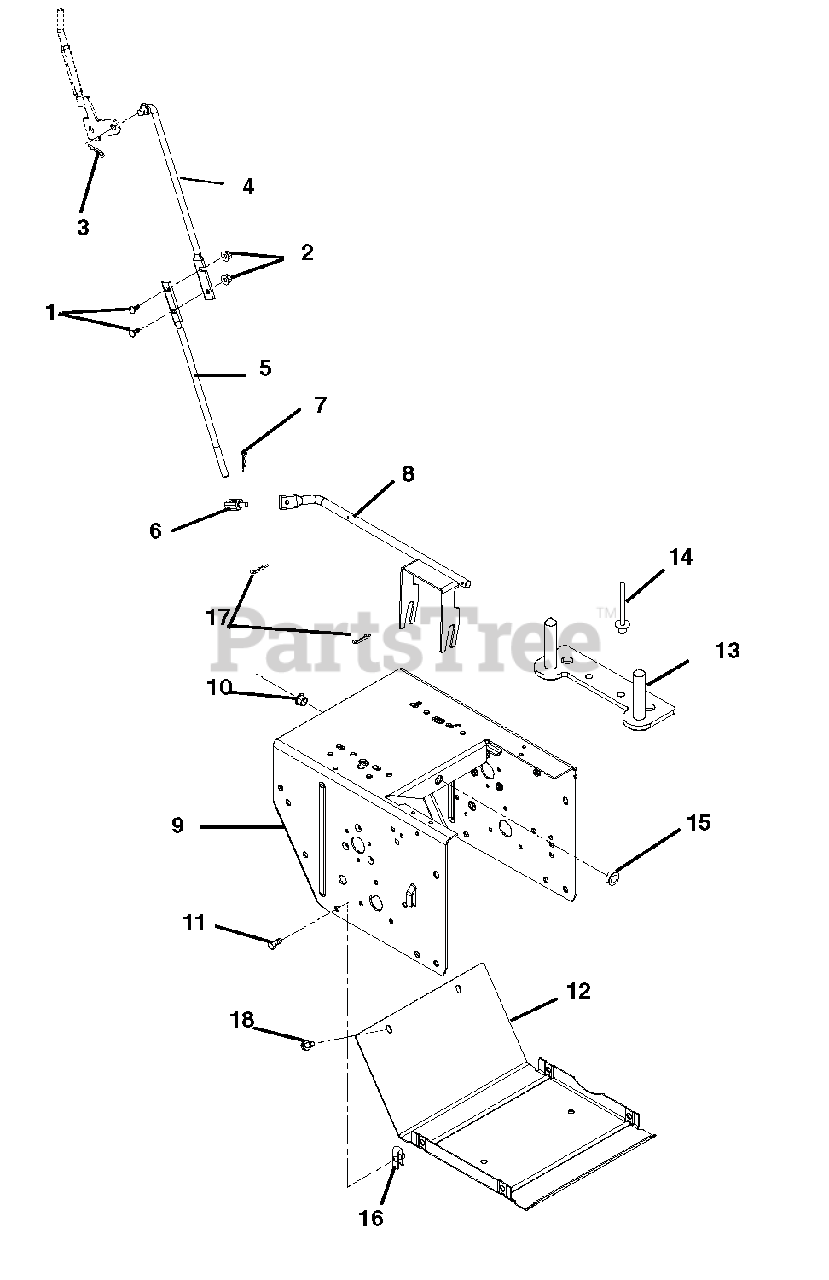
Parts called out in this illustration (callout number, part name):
1	@BLT-RDHDSQNK .25-20X.75 G5YZ
2	@NUT-LK-TOP-FLG .25-20 YWZC
3	PIN-HAIR, ENDRIES #25 YWZC
4	ROD, SHIFT-UPPER
5	ROD, SHIFT-LOWER
6	PIVOT,SHIFT ROD .375-16(TRUNN)
7	PIN-HAIR, ENDRIES #25 YWZC
8	ARM, SHIFT-WELDMENT
9	FRAME, MAIN
10	BUSHING, POLYLINER-.50 SPLIT
11	BLT-HEX .25-20X.75 HWH YZ GR5
12	COVER, BOTTOM
13	STRAP, ENGINE BOLT-WELDMENT
14	RVT-POP .187 YZ
15	BUSHING, POLYLINER-.50 SNAPIN
16	NUT-RTNR .25-20X.56
17	CLIP, SPRING
18	SCR-TAP .25-20X.50 HWH TR YWZ
